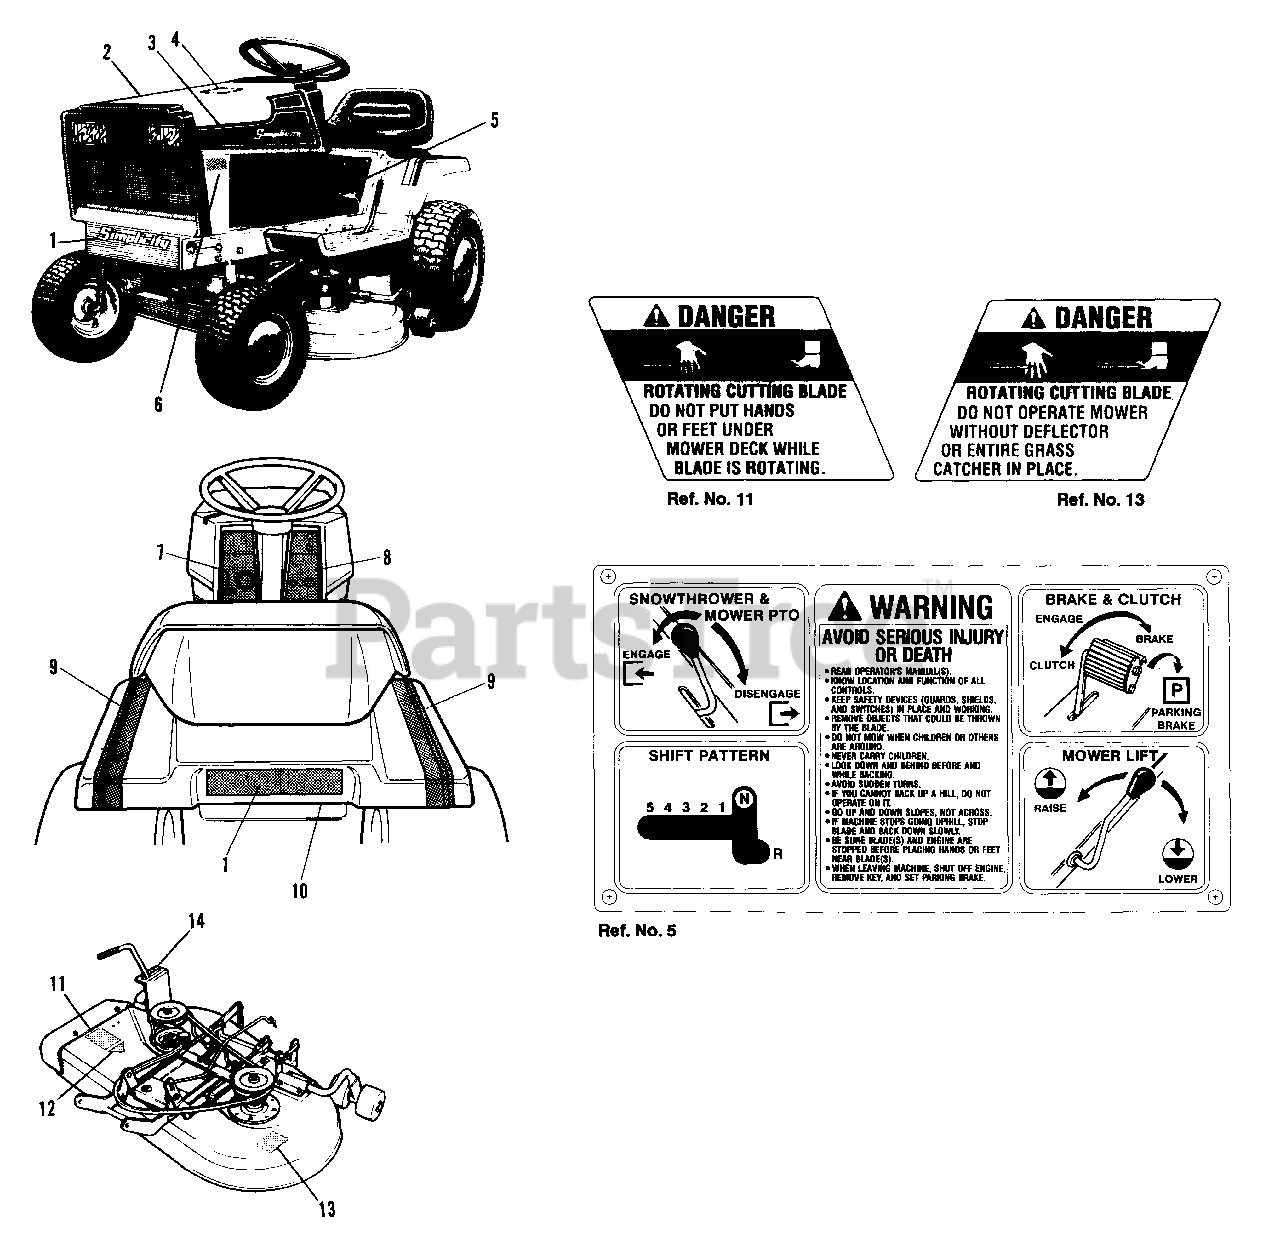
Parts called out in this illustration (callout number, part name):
1	DECAL, Simplicity
2	DECAL, Hood, R.H.
3	DECAL, Hood, L.H.
4	DECAL, Drive Belt
5	DECAL, Shift Pattern
6	DECAL, 4208 Electric
6	DECAL, 4210 Electric
6	DECAL, 4211 Electric
6	DECAL, 4212 Electric
7	DECAL, Dash, L.H. Side
8	DECAL, Dash, R.H. Side
9	DECAL, Seat Deck
10	DECAL, Battery
11	DECAL, Danger
12	DECAL, OPEI
13	DECAL, Danger
14	DECAL, Mower Height
